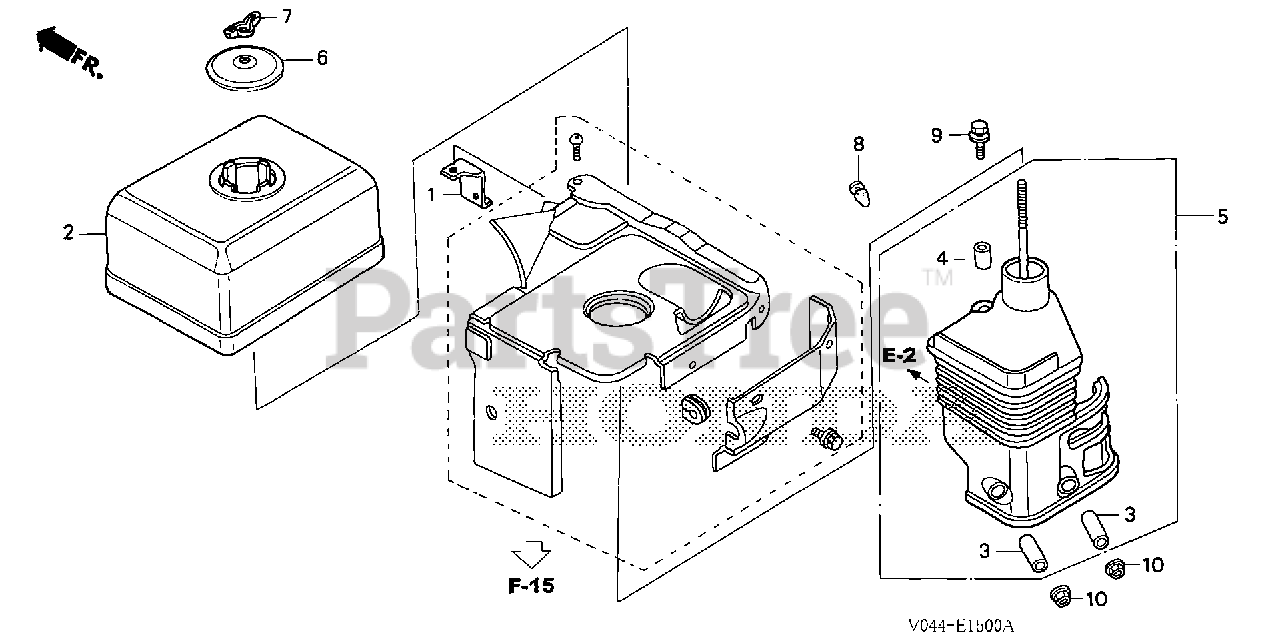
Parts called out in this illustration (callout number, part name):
1	STAY, ENGINE CONTROL COVER
2	COVER, AIR CLEANER (SEMI-DRY)
3	COLLAR, AIR CLEANER Use from Engine SN 1786085.
4	COLLAR B, AIR CLEANER
5	ELBOW, AIR CLEANER
6	CAP, AIR CLEANER
7	WINGNUT, TOOL BOX SETTING
8	PLUG, CONE TYPE
9	BOLT, FLANGE (6X20)
10	NUT, FLANGE (6MM)
